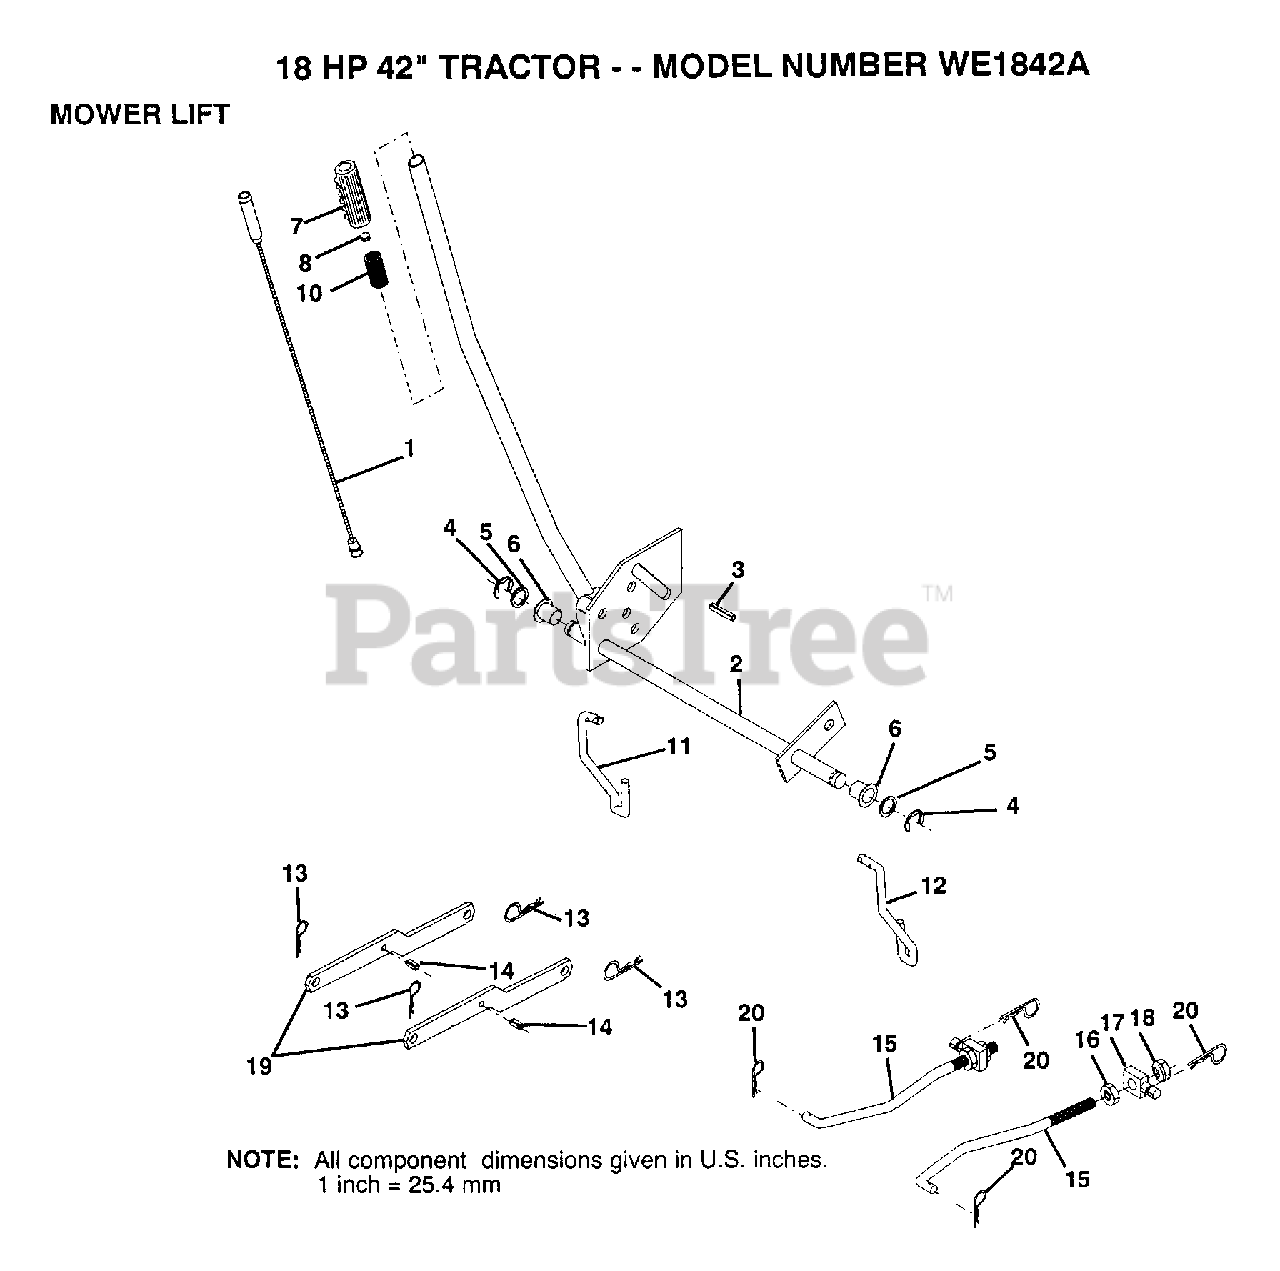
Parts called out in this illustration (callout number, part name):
1	WIRE ASM
2	SHAFT.ASM.LIFT LH
3	PIN GROOVE
5	WASHER
6	NYLON BEARING
7	GRIP
11	LINK LIFT LH
12	LIFT LINK RH
14	"PIN,SPRING"
15	LINK.FRONT
16	NUT
17	TRUNION
18	NUT.LK.W/WSH.1/2.
20	RETAINER.SPRING
